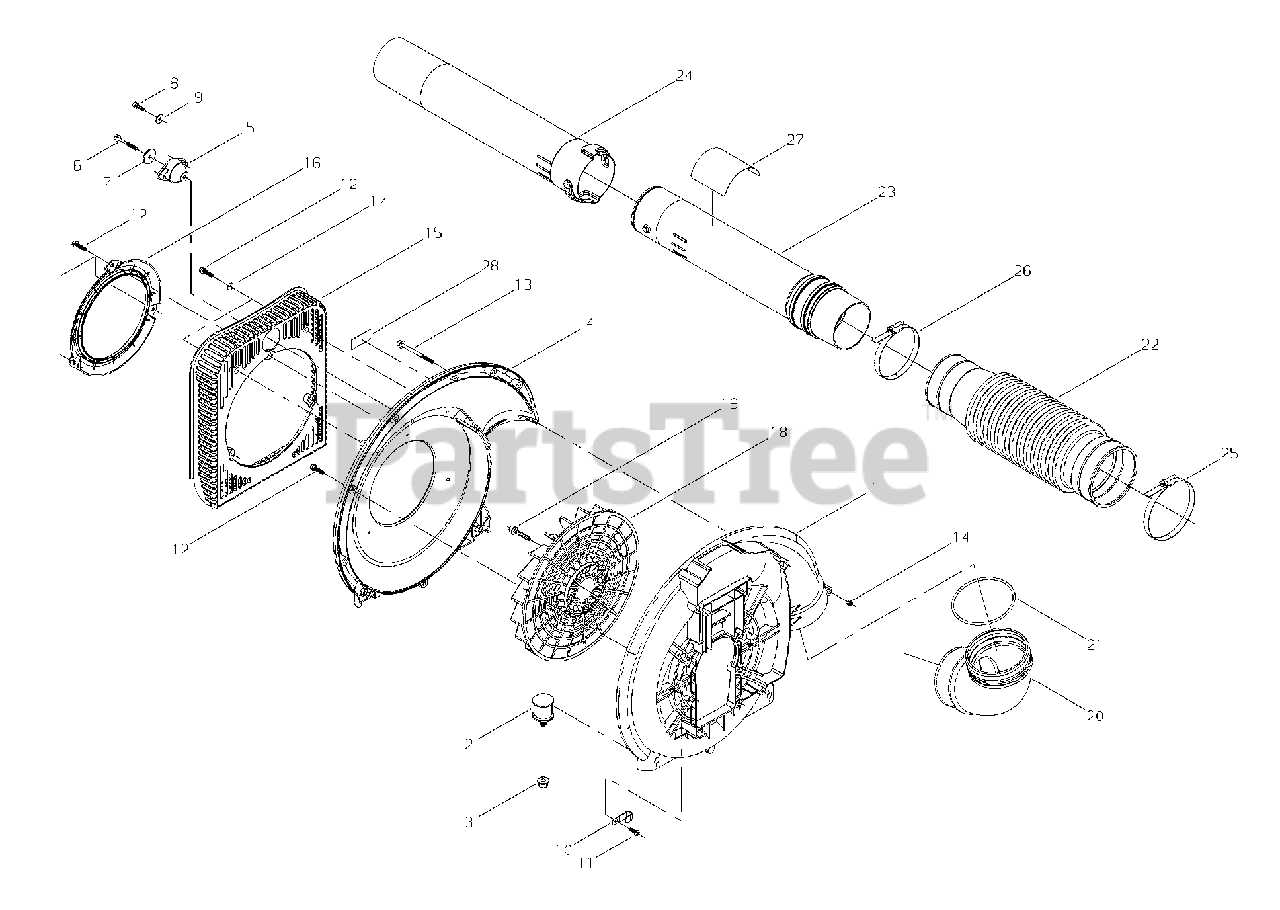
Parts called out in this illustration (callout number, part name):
1	COVER, FAN - OUTER
2	CUSHION, AV 6
3	NUT, FLANGE M6
4	COVER, FAN - INNER
5	CUSHION, AV 5
6	BOLT TAPPING M5
7	WASHER Ø25ר5.5×2
8	BOLT M5×16
9	WASHER Ø15ר5.2×1.6
10	CLIP
11	SCREW, TAPPING 5×14
12	BOLT M5×20
13	BOLT M5×70
14	NUT M5
15	COVER, INTAKE
16	COVER, DEBRIS GUARD
17	WASHER 5 MM
18	FAN
19	BOLT M6×35
20	BEND PIPE
21	O-RING
22	TUBE, BLOWER - FLEXIBLE
23	TUBE, BLOWER - SWIVEL
24	TUBE, BLOWER - NOZZLE
25	CLAMP
26	CLAMP
27	LABEL, TRADE
28	LABEL, CAUTION - AIR INTAKE
